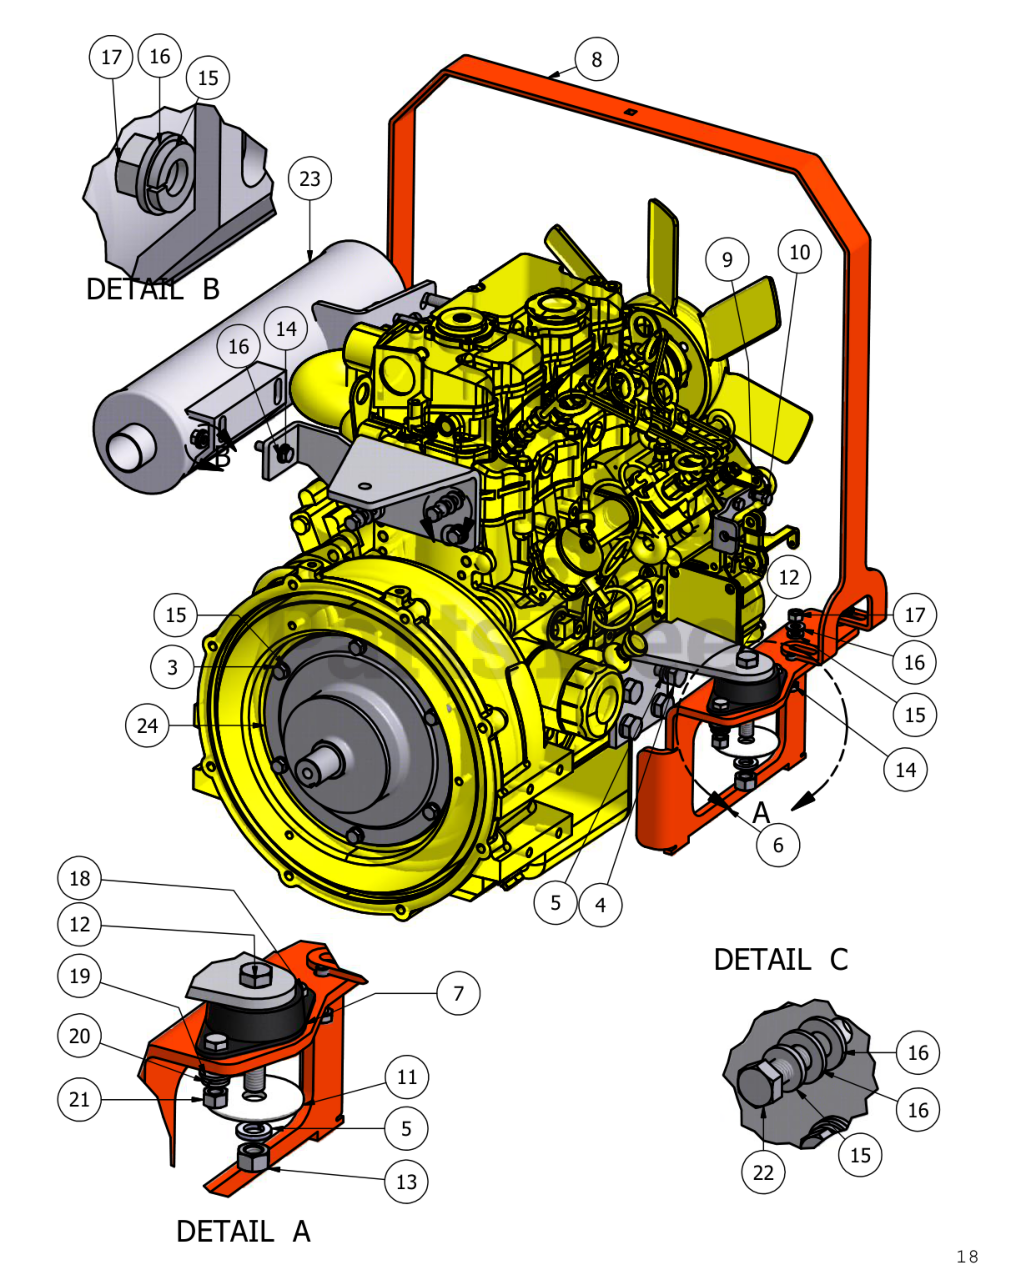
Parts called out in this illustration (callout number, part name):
1	28 hp Caterpillar Engine
2	35hp Caterpillar Engine
3	5/16" x 1" Bolt
4	12mmx25mm Bolt
5	1/2" Lock Washer
6	28hp Diesel Frame
6	35hp Diesel Frame
7	Rubber Isolator
8	Hood Holder
9	1/4" Lock Washer
10	6mm x 20mm Bolt
11	Snubbing Washer
12	1/2" x3" Hex Bolt
13	1/2" Hex Nut
14	5/16" x 1 1/4" Hex Bolt
15	5/16" Lock Washer
16	5/16" Flat Washer
18	3/8"x1" Hex Bolt
19	3/8"Flat Washer
20	3/8" Lock Washer
21	3/8" Hex Nut
22	8mmx25mm Bolt
23	Diesel Muffler
24	Stub Shaft
